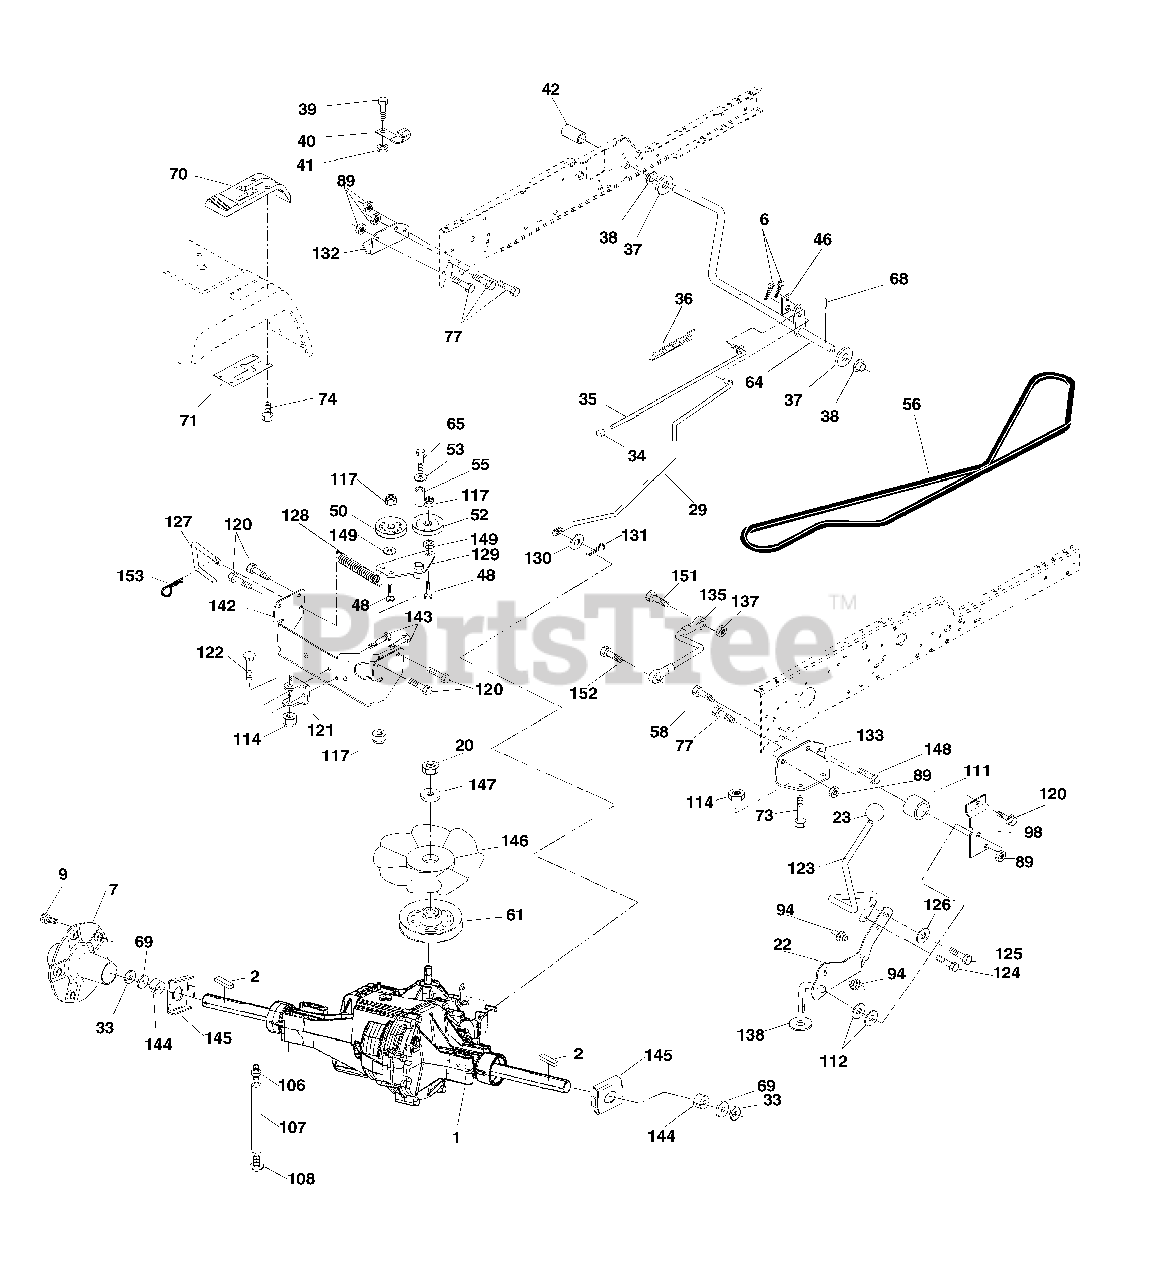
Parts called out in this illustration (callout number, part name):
2	Key Sq. 1/4 x 1/4 x 2
6	Pin, Cotter
7	Wheel, Hub Assembly
22	Lever Asm Shift
29	Brake, Rod
34	Cap, Parking Brake
35	Rod, Parking Brake
36	Spring, Drive Ground
37	Washer 25/32 x 1-1/4 x 16 Ga.
39	Screw, Fin. #10-24 x 1
40	Actuator, Interlock VGT
41	Nut Centerlock 10-24 Unc
42	Cover, Pedal
46	Retainer, Spring
48	Bolt Rdhd 3/8-16 x 1.3/4 Gr. 5
50	Pulley, Idler, Flat
52	Pulley, Idler, Grooved
53	Washer, Hardened
55	Bearing, Idler
58	Bolt Fin Hex 7/16-14 x 1-1/2
61	Pulley, Transaxle
64	Shaft, Brake Pedal
65	Bolt, Shoulder
70	Console Automatic YT/GT
71	Plate Console Shift
73	Bolt Hex Flghd 5/16-18 x 3 Gr5
74	Screw Hex Wsh. Hi-Lo 1/4-1/2
77	Bolt Fin Hex 7/16-14 x 1
89	Nut Crownlock 7/16-14 Unc
94	Fastener Christmas Tree
98	Bracket Shift
106	O-Ring Asm Hydro Gear
107	Line Fuel Hydro 15" VGT
108	Cap Asm Vent Hydro Gear
111	Spacer Shift Lever VGTH
112	Washer Nylon High Temp
114	Nut Lock Hex W/Ins 5/16-18 Unc
117	Nut, Lock Flg. 3/8-16
120	Screw 3/8-16 x .75
121	Bracket Strap Torque
122	Bolt RDHDSQ 5/16-18 Unc x 2-1/2
124	Bolt Shoulder 5/16-18 x .561
125	Screw 5/16-18 x 5/8
126	Washer SRRTD 5/16 ID x 1.0 x .125
127	Link Control Clutch
128	Spring Drive GRND
129	Bracket Asm Idler Tensioning
130	Washer 13/32 x 5/8 x 16 Ga.
131	Pin Cotter 3/32 x 3/4
132	Bracket Mtg Hydro 3500 LH VGT
133	Bracket Mtg Hydro 3500 RH VGT
135	Link Asm Control Hydro 3500
137	Nut Lock 5/16-18 NC Thd.
138	Washer Thrust 5/8 x 1.10 x 1/32
142	Strap Torque HG-3500
143	Screw Thdrol 5/16-18 x 3/4
144	Washer Spacer Axle HG-3000
145	Washer Axle Flange HG-3000
146	Fan 7" Hydro
148	Screw 3/8-16 x 1.0
149	Washer 13/32 x 7/8 x 10 Ga.
151	Bolt Hex 5/16-18 x 7/8
152	Bolt Hex 5/16 x 1 W/Patch
153	Spring, Retainer
